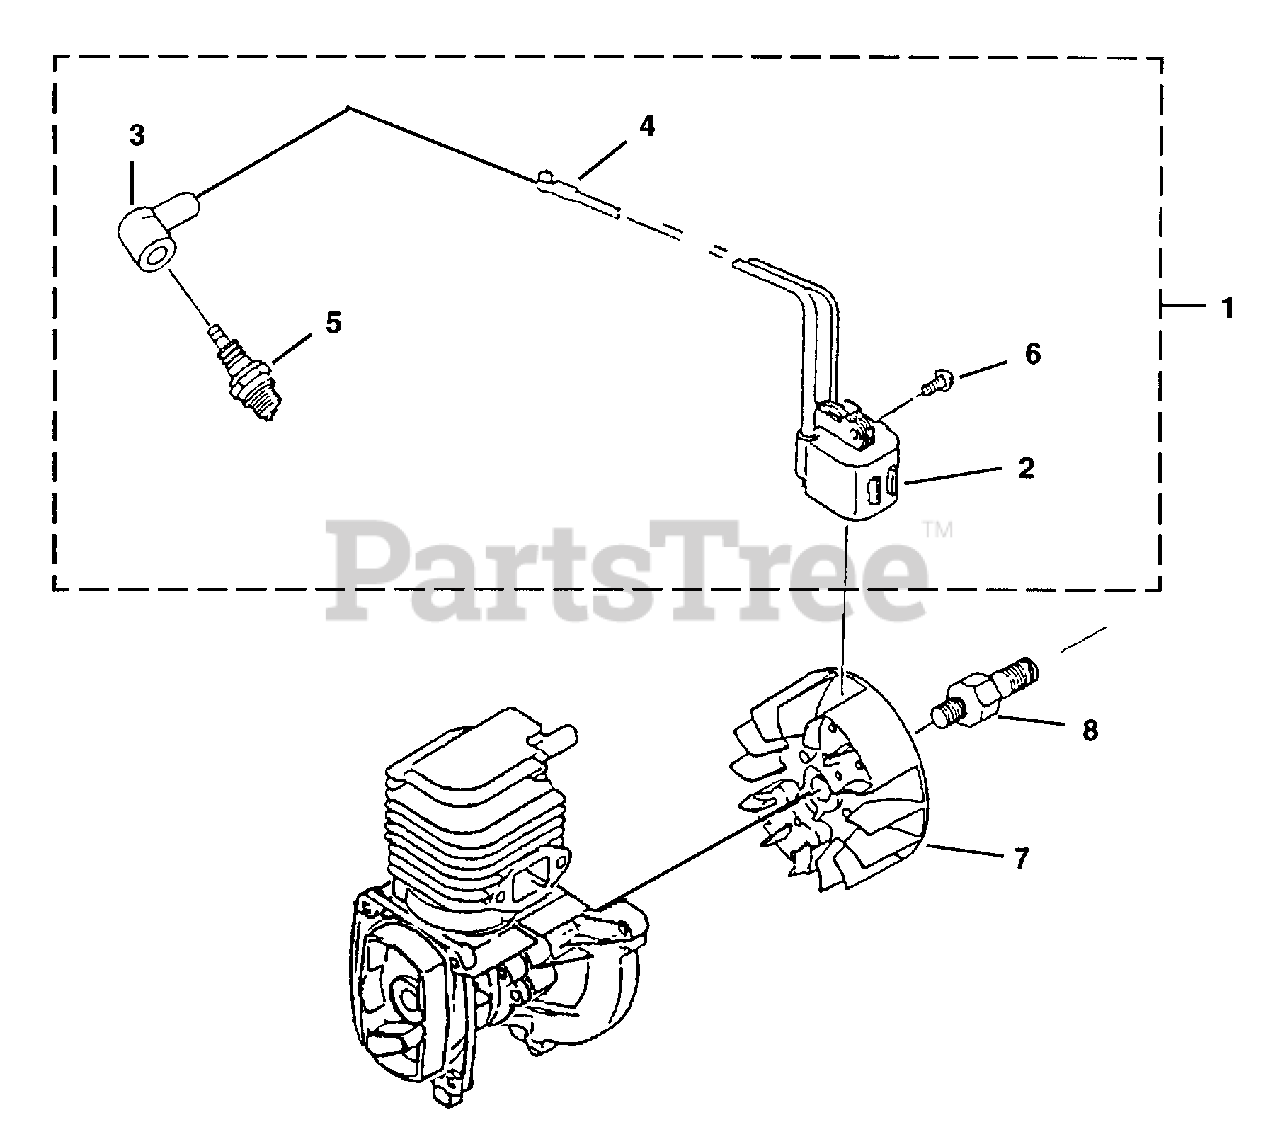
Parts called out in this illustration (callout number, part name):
1	IGNITION KIT
2	MODULE-Ignition
3	CAP-Plug
4	SPRING-Plug Cap
5	SPARK PLUG
6	SCREW ASSEMBLY (M4 x 20)
8	SHAFT-Fan
